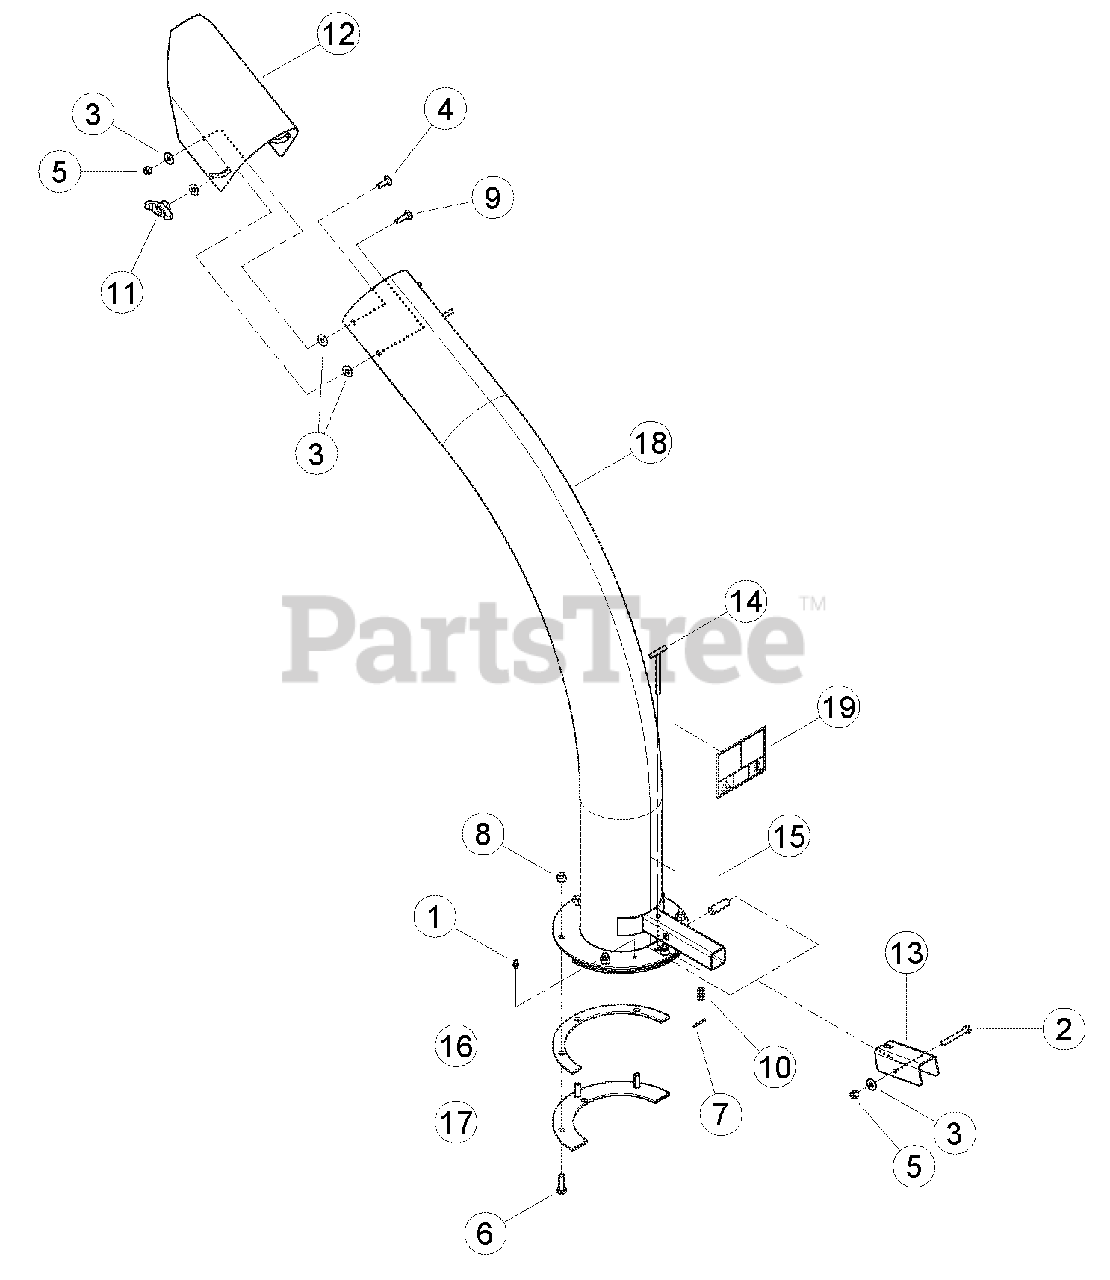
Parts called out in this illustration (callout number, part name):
1	FITTING, 1/4 SELF-TAP GREASE
2	BOLT, 5/16 X 2-1/2 HEX HD GR5 ZP
3	WASHER, 5/16 FLAT ZP
4	BOLT, 5/16 X 1 CRG GR5 ZP
5	NUT, 5/16 NE NYLOCK ZP
6	BOLT, 3/8 X 1-1/4 HEX HD GR5 ZP
7	PIN, 1/8 X 1.00 COTTER ZP
8	NUT, 3/8 NE NYLOCK ZP
9	BOLT, 5/16 X 1-1/4 CRG GR5 ZP
10	SPRING, LOCK COMPRESSION
11	KNOB, 5/16-18 UNC TEE W/LOCKING INSERT
12	DEFLECTOR, BLOWER-VAC DISCHARGE
13	LEVER, DISCHARGE LOCK
14	WELDMENT, DISCHARGE LOCK PIN
15	TUBE, DISCHARGE LOCK PIVOT
16	SPACER, DISCHARGE PIVOT
17	RING, DISCHARGE CLAMP
18	ASSEMBLY, 6 INCH DISCHARGE SERVICE PART
19	DECAL, DISCHARGE DEBRIS & LOCK
